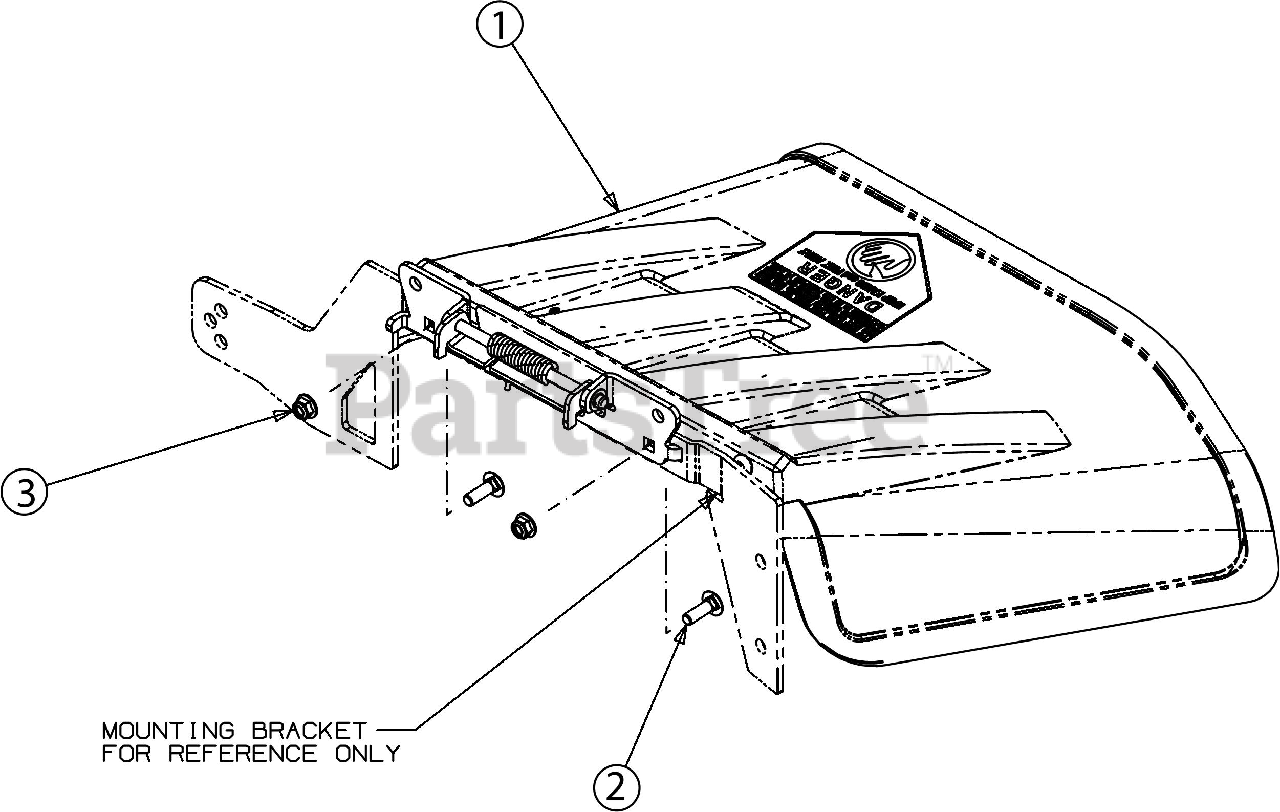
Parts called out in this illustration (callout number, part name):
1	CHUTE ASSEMBLY
1	CHUTE DEFLECTOR BRACKET
1	CHUTE MOUNTING BRACKET
1	PUSH CAP
1	TORSION SPRING
1	TORX SHOULDER SCREW 1/4-20
1	BAGGER CHUTE ROD
2	CARRIAGE BOLT 5/16-18 X 1.00
3	FLANGE LOCK NUT 5/16-18
